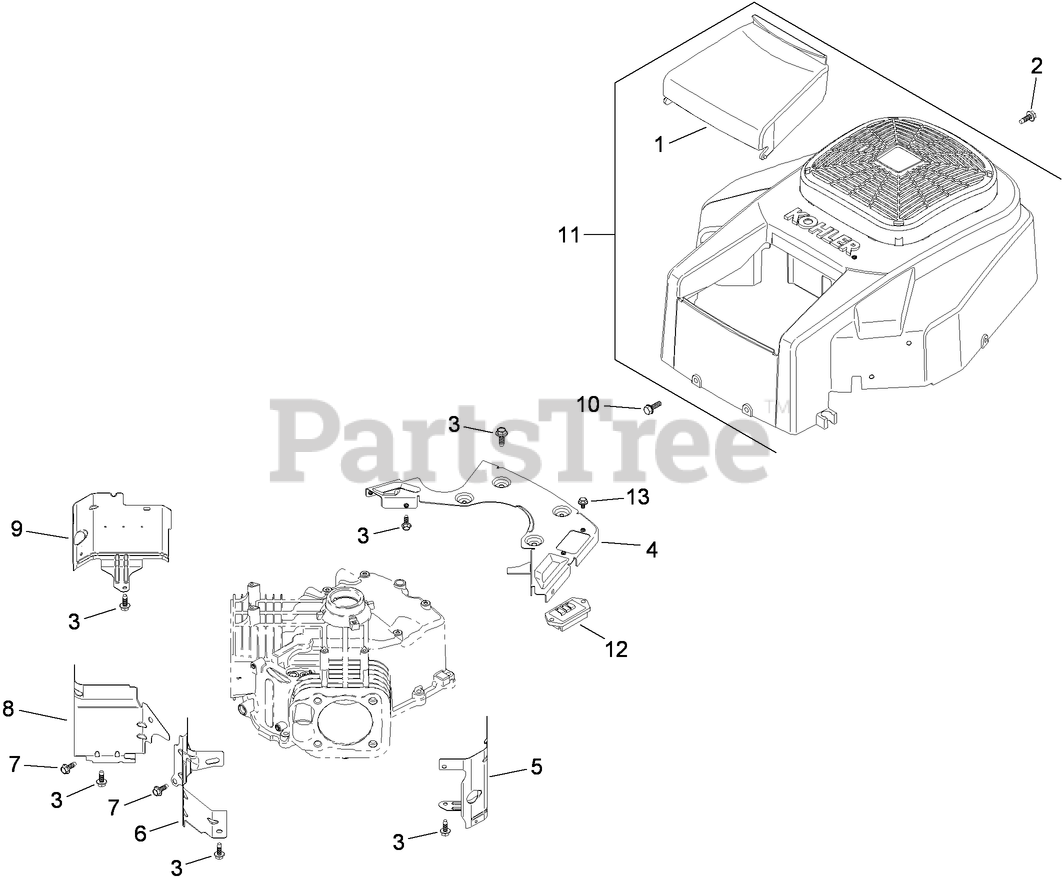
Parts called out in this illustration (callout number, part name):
1	COVER-CLEANER, AIR
2	SCREW-FLANGE, THREAD FORMING (M5X0.8X16)
3	SCREW-FLANGE, THREAD FORMING (M6X1.0X16)
4	PLATE-BACKING
5	BAFFLE-BARREL, CYLINDER (No.2 SIDE)
6	BAFFLE-VALLEY (No.2 SIDE)
7	SCREW-HHFTF (M5X.80X10)
8	BAFFLE-VALLEY (No.1 SIDE)
9	BAFFLE-BARREL, CYLINDER (No.1 SIDE)
10	SCREW-TAP (M6X1.7X18)
11	BLOWER HOUSING ASM (FIXED GUARD) (INCLUDES 2, 3)
12	RECTIFIER/REGULATOR
13	SCREW-FLANGED, THREAD FORMING (M6X1.0X11)
